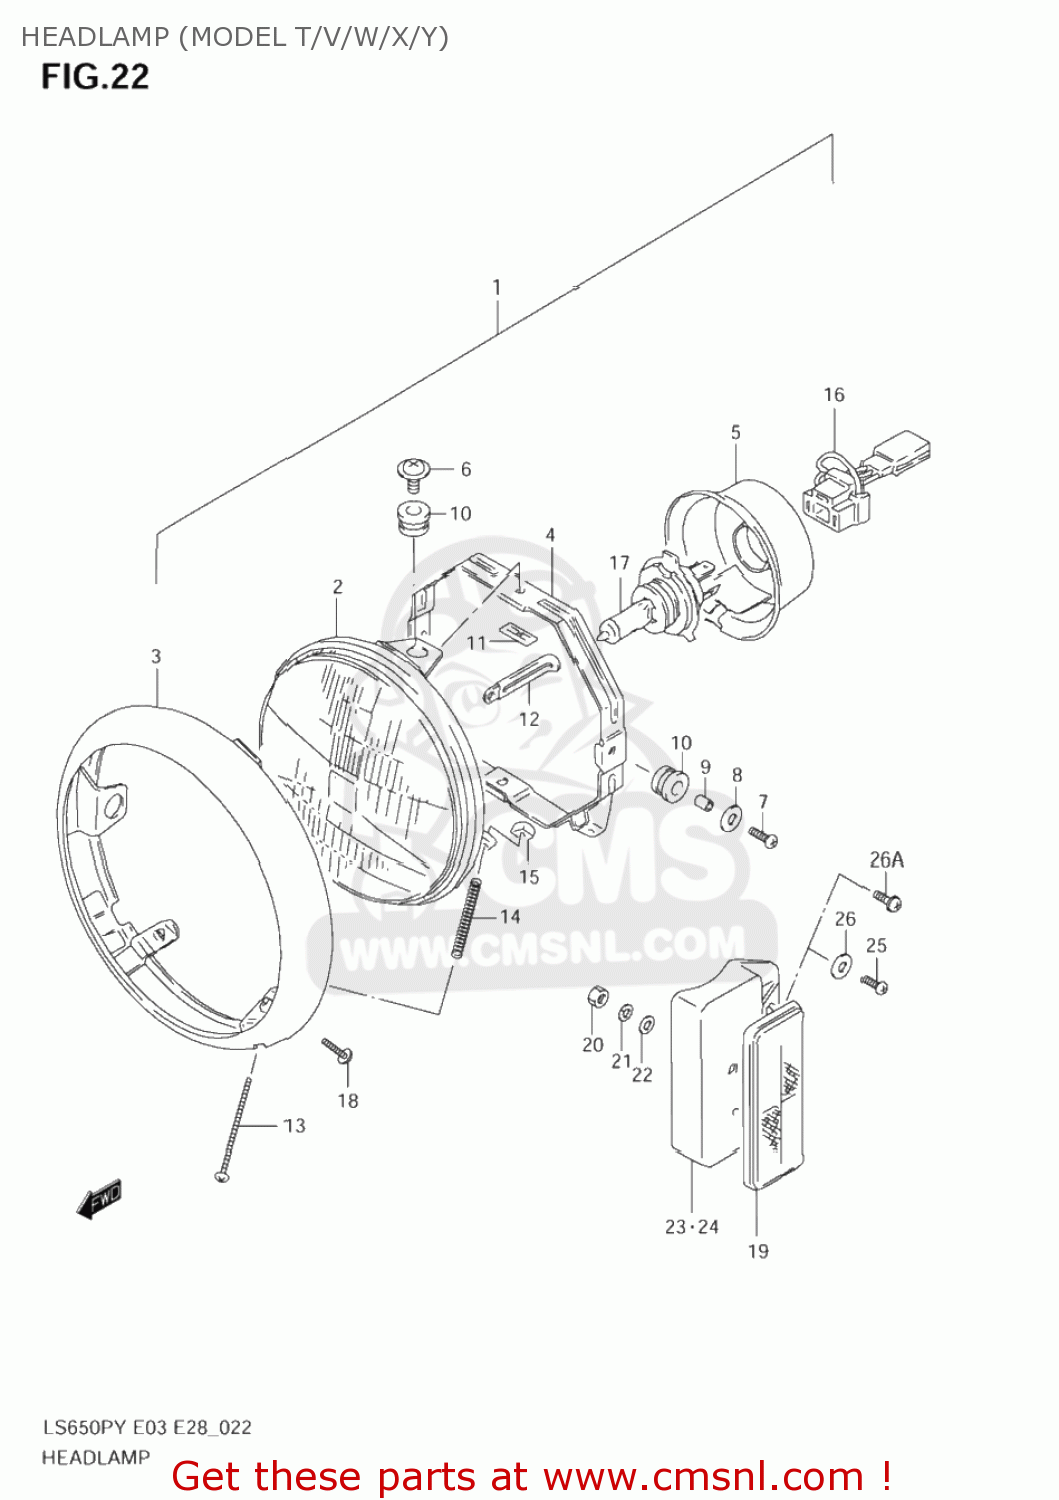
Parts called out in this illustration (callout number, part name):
1	HEADLAMP ASSY
2	UNIT,LAMP
3	RIM
4	RING,MOUNTING
5	COVER,SOCKET
6	SCREW,MOUNTING
7	SCREW(5X14)
8	WASHER (5.5X18X1)
9	SPACER
10	CUSHION
11	NUT
12	CLAMP(L:45)
13	SCREW,ADJUSTING(4X50)
14	SPRING
15	NUT,HEADLAMP ADJUST
16	SOCKET
17	BULB(12V60/55W,H4)
18	SCREW
19	REFLEX REFLECTOR,FR SIDE
20	NUT
21	LOCK,WASHER
22	WASHER(5.2X16X1)
23	BRACKET,FR SIDE RR,R
24	BRACKET,FR SIDE RR,L
25	SCREW 5X12
26	WASHER(5.5X16X1.2)
26A	SCREW(5X12)
